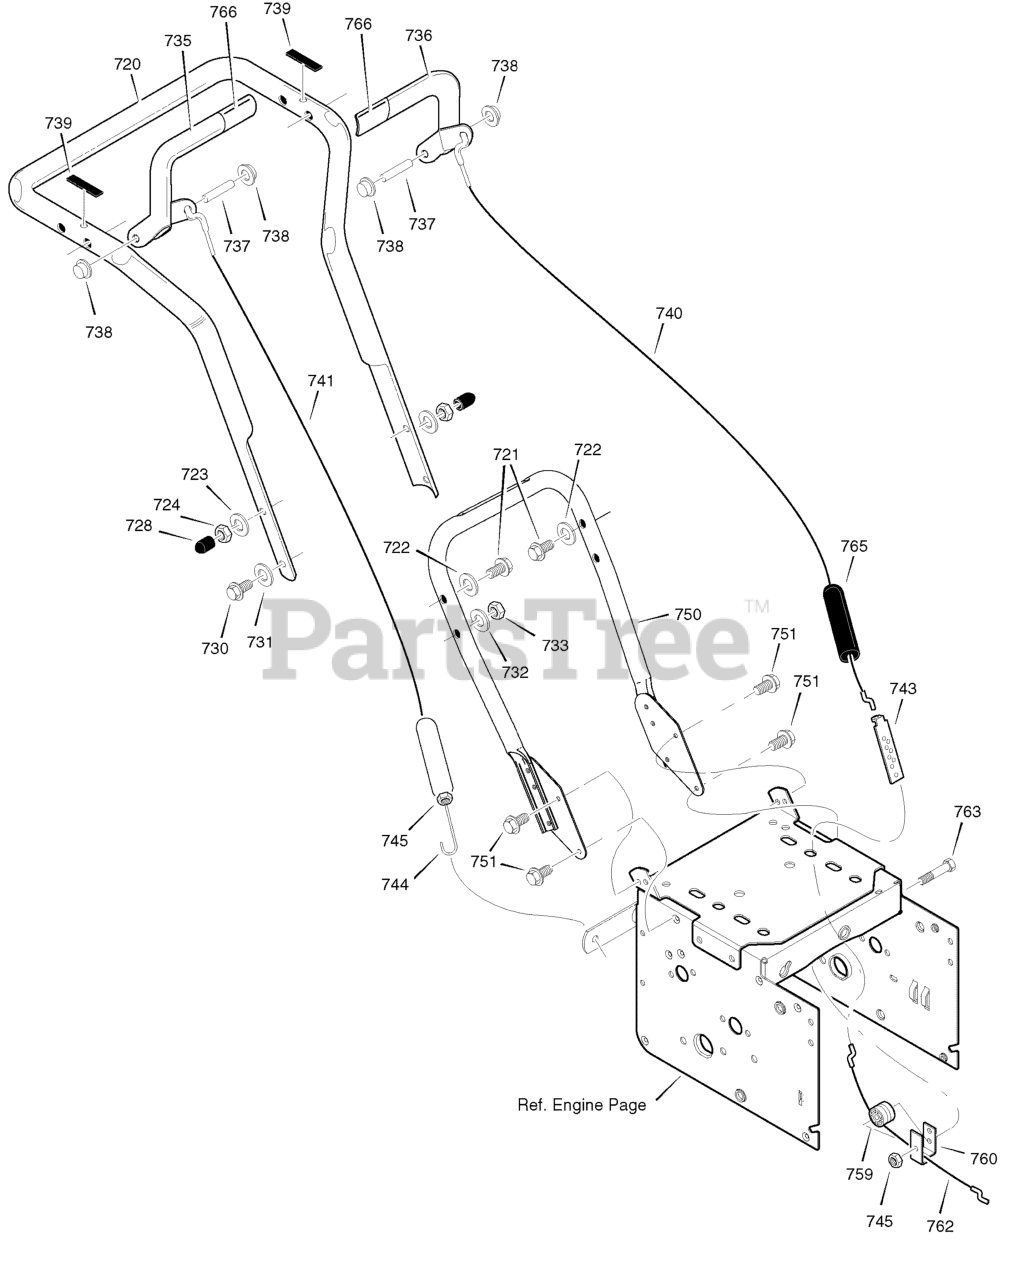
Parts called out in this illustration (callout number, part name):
720	HANDLE, UPPER
721	SCREW, 3/8- 16 X 3
722	WASHER, Flat, 13/32
723	WASHER
724	NUT, 3/8- 16
728	STOP, PLASTIC
730	SCREW, 3/8- 16 X 2
731	WASHER, Flat, 13/32
732	WASHER
733	NUT, 3/8- 16
735	HANDLE, RIGHT
736	HANDLE, LEFT
737	PIN, PIVOT CLUTCH
738	NUT, PUSH ON CAP
739	BUMPER, RECTANGLE
740	CABLE, DRIVE
741	CABLE, AUGER CLUTCH
743	BRACKET, CABLE ADJUSTER
744	SPRING, AUGER CLUTCH
745	NUT, 1/4- 20
750	HANDLE, LOWER
751	SCREW, TAP 5/16-18 X .75
759	SPOOL-CABLE, AUGRT CLUTCH
760	BRACKET, CABLE SPOOL YZ
762	CABLE, LOWER DRIVE 12"
763	BOLT, HEX 1/4-20 X 1.5
765	BOOT, CLUTCH SPRING
